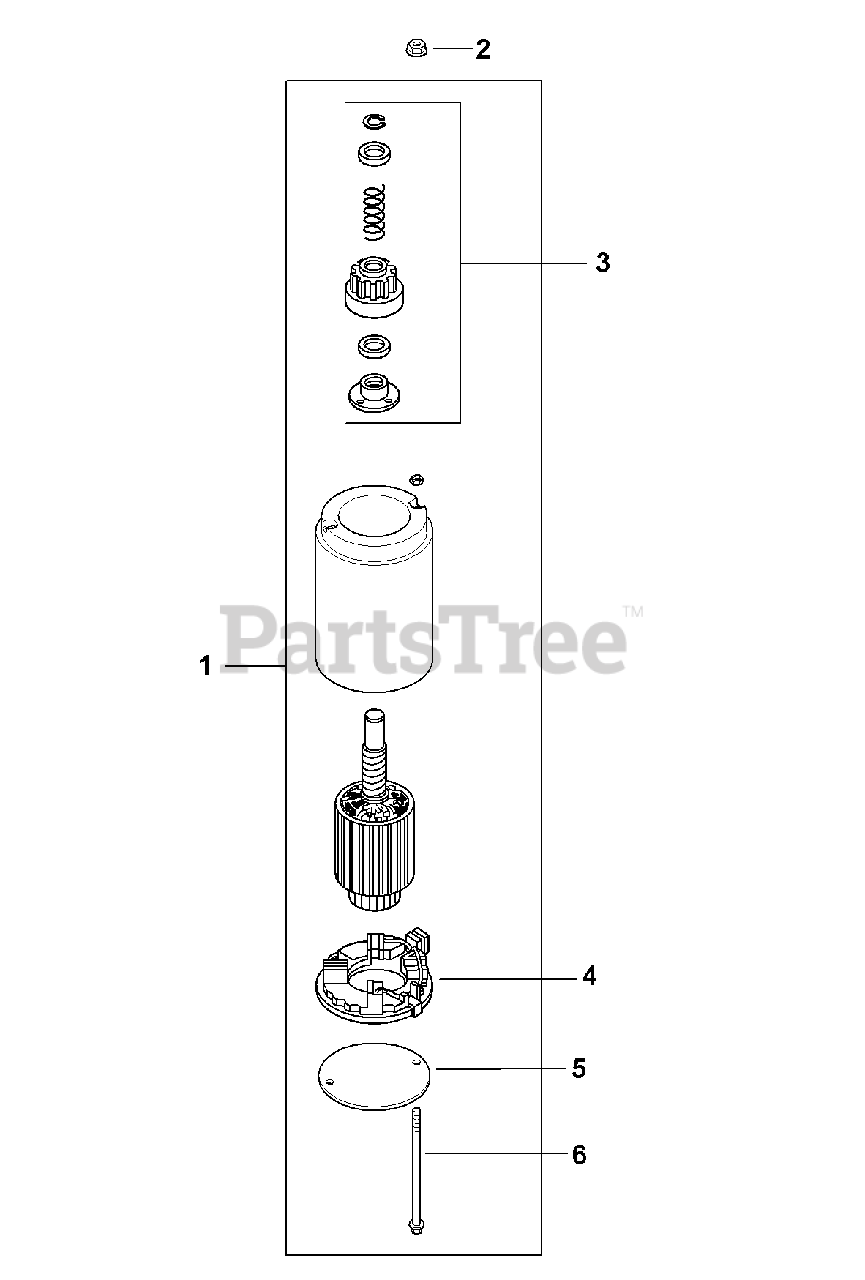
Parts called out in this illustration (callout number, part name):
1	Starter Assembly (Inc. 3-6)
2	Free Spinning Flg. Nut, #10-24
5	Drive End Cap (J.E.)
